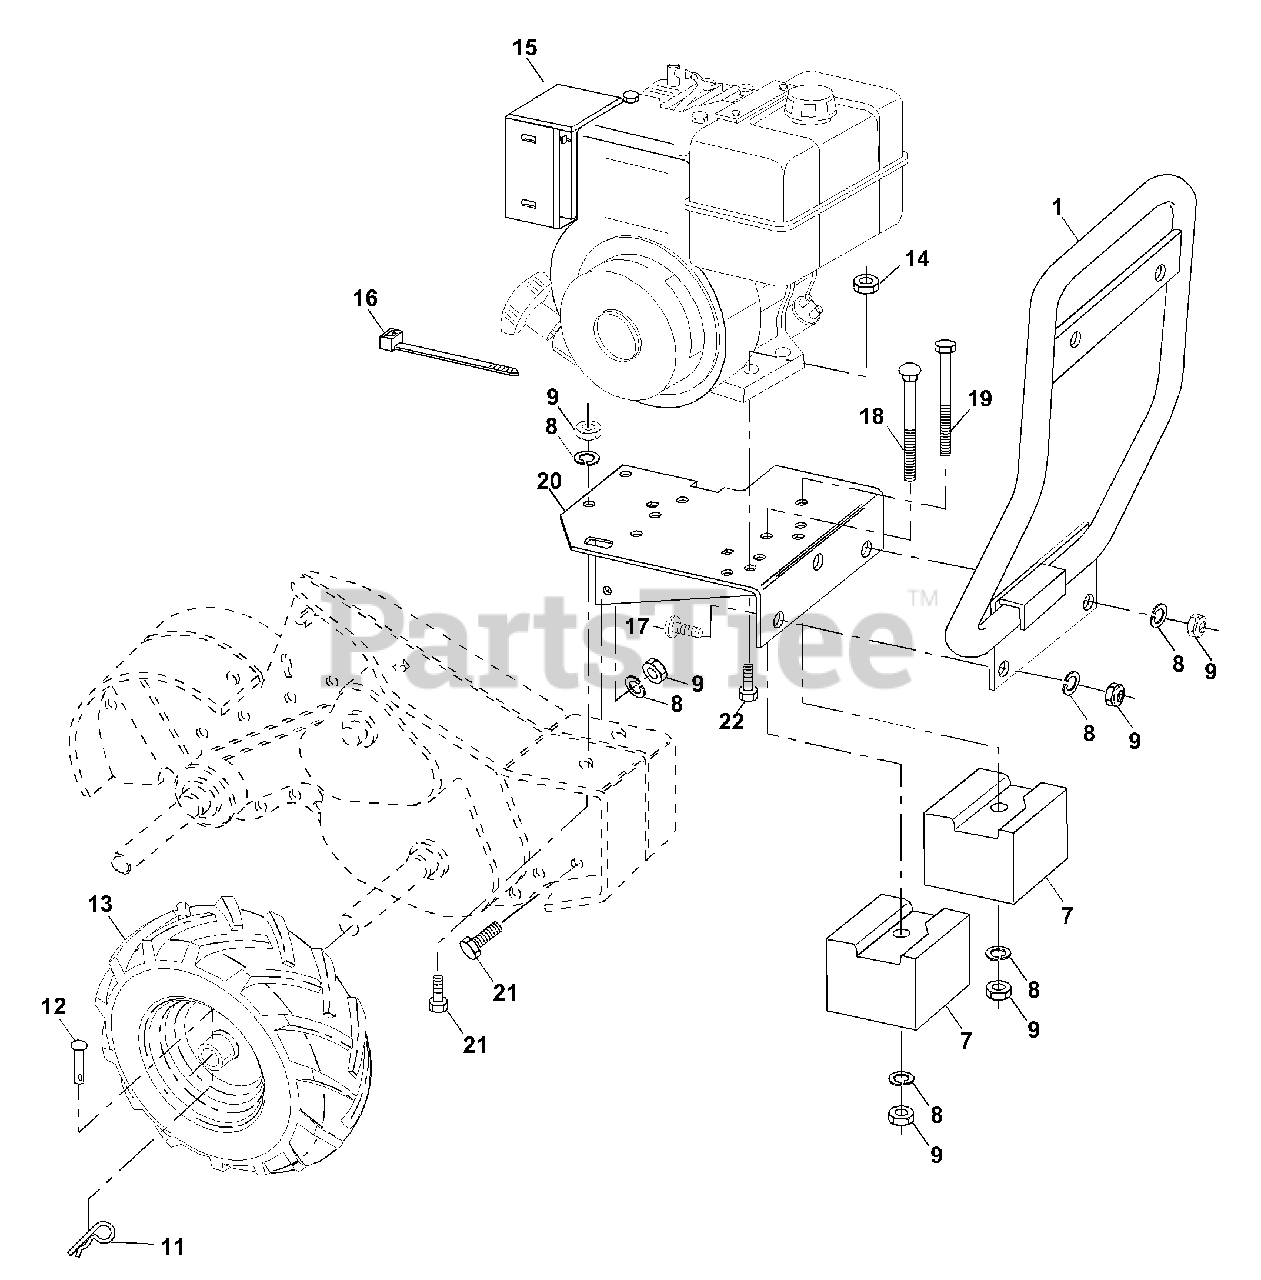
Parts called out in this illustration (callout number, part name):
7	Counter Weight,R.H.
8	Washer, Lock 3/8
9	Nut, Hex 3/8-16
11	Clip,Hairpin
12	Rivet, Drilled
13	Rim
13	Tire Valve
14	Nut, Keps 5/16-18
16	Tie, Cable
17	Bolt, Carriage 3/8-16 x 1
18	Bolt, Carriage 3/8-16 x 4-1/2
19	Bolt, Hex Head 3/8-16 x 4-1/2
20	Bracket, Engine
21	Bolt, Hex Head 3/8-16 x 1
22	Bolt, Hex 5/16-18 x 1-3/4
